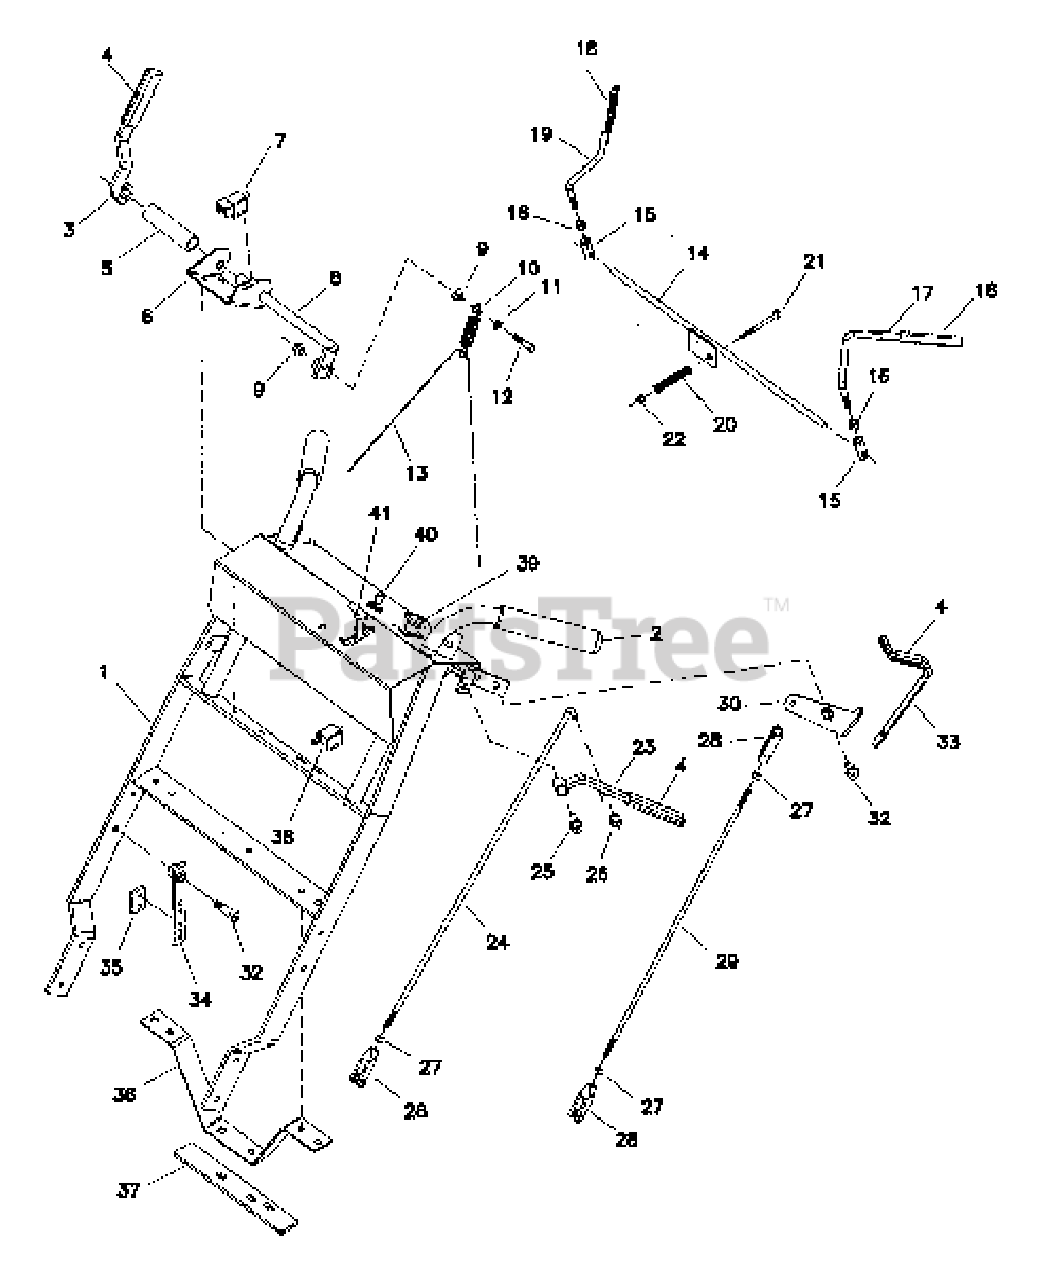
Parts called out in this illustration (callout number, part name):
1	HANDLE BAR ASSEMBLY
2	GRIP, Foam
3	BRAKE HANDLE, Complete (Includes Ref 4)
4	GRIP, Foam
5	BRAKE SHAFT COVER
6	BRAKE HANDLE MOUNT
7	SWITCH, Brake
8	BRAKE HANDLE SHAFT
9	NUT, Hex, Serrated Flange, 5/16-18
10	SPRING, Extension
11	WASHER, 5/16
12	CAPSCREW, Hex Head, 5/16-18 x 1-1/2
13	BRAKE CABLE
14	SWITCH ROD
15	HEX ADJUSTER
16	NUT, Hex, 5/16-18
17	HANDLE, Operator Presence, RH, Complete (Includes Ref 18)
18	GRIP, Vinyl
19	HANDLE, Operator Presence, LH, Complete (Includes Ref 18)
20	SPRING, Compression
21	CAPSCREW, Hex Head, 1/4-20 x 3
22	NUT, Hex, Nylon Lock, 1/4-20
23	BRAKE HANDLE, Complete (Includes Ref 4)
24	BRAKE HANDLE ROD
25	SHOULDER BOLT, 1/2 x 1-1/2
26	COLLAR, 5/16 Set
27	NUT, Hex, 5/16-24
28	CLEVIS, Plastic, 5/16
29	THUMB CONTROL ROD
30	CONTROL PIVOT, RH
32	SHOULDER BOLT, 1/2 x 1
33	THUMB CONTROL LEVER, Complete (Includes Ref 4)
34	BRAKE PIVOT
35	CABLE CLAMP
36	SUPPORT, Handle Bar
37	SUPPORT, Engine Deck
38	SWITCH, Operator Presence
39	SWITCH, PTO
40	SWITCH, Ignition
41	CABLE, Throttle
